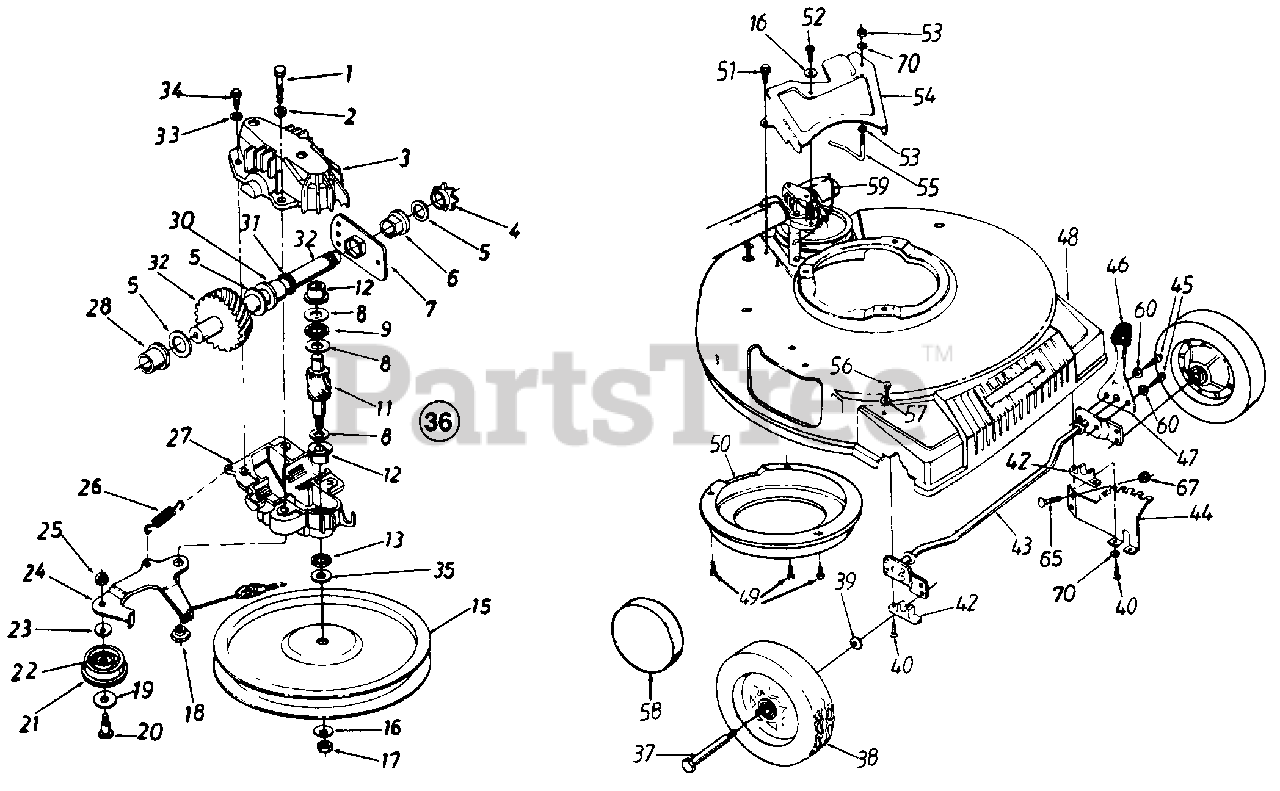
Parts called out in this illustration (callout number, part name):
1	Hex Patch Bolt 1/4-20 x 1.25"
2	L-Wash. 1/4" I.D.
3	Upper Hsg. Shaft
4	#48 Sprocket 7 T x 1/2 Pitch
5	Fl-Wash. 5/8" I.D. x .030
6	Hex Flange Brg. .631" I.D.
8	Thrust Wash. .382" I.D. x .70" O.D.
9	Thrust Bearing .375" I.D. x .812" O.D.
11	11 Tooth Pinion Shaft
12	Flange Bearing
13	Oil Seal
15	Fl-Pulley 5.06" O.D.
16	Bell-Wash. .265" I.D. x .75"
17	Hex L-Nut 1/4-28 L.H. Thd.
18	Shld. Spacer .375" Dia. x .170
19	Fl-Wash. .390" I.D. x 1.0"
20	Shld. Bolt .375" Dia. x .40"
21	Fl-Idler Plastic 1.50" Dia.
22	Needle Brg. .375" x .31
24	Idler Brk't. Ass'y.
25	Hex Patch L-Nut 1/4-28 Thd.
26	Extension Spring 1.12" Lg.
27	Lower Hsg. Half
28	Flange Bearing .566 Dia.
30	Flange Bearing .629 Dia.
31	Oil Seal .625 Dia.
32	Gear Shaft Ass'y.
33	L-Wash. #10 I.D.
34	Hex Tap Scr. #10 x .62"
35	Hex Washer .26" x .88"
36	Transmission Comp.
37	Front Axle Bolt
38	Wheel Ass'y. Comp.
39	Bell-Wash. .380" I.D. x .88
40	Hex Wash. Hd. Scr. 1/4 x 1" Lg.
42	Block Bushing
43	Axle Ass'y.
44	Height Adj. Bracket
45	Hex TT-Tap Scr. 1/4-20 x .38"
46	Knob
47	Spring Lever
48	Plastic Front End
49	Hex B-Tap Scr. 1/4" x .38"
50	Belt Cover
51	Hex Wash. Hd. TT-Scr. 1/4-20
52	Hex Wash. Hd. B-Tap Scr. 1/4 x .62" (Spec.)
53	Hex Nut 1/4-20 Thd.
56	Torx Truss Hd. Scr. 5/16 x .75"
57	Bell-Wash. .345" I.D. x .88"
58	Hub Cap
59	S.P. Cable
60	External L-Wash. 1/4" I.D.
65	Carr. Bolt 1/4-20 x .5" Lg.
67	Hex Flange L-Nut 1/4-20 Thd.
70	L-Wash. 1/4" I.D.
